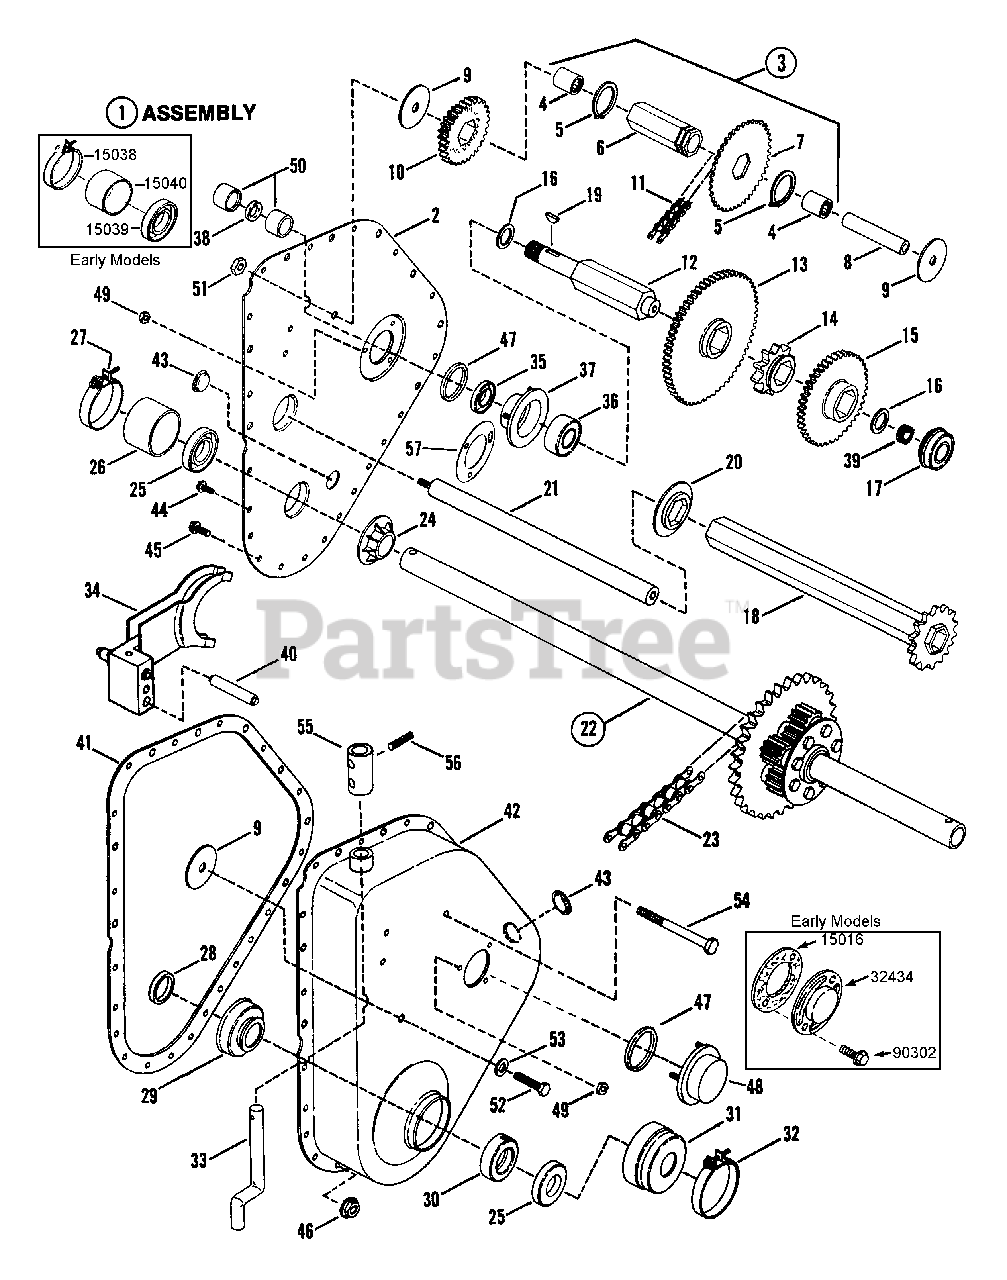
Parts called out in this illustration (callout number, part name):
1	ASSEMBLY, TRANSMISSION (NLA)
2	COVER, Transmission
3	ASSEMBLY, Hex Tube (2.5" Long)
4	BEARING, Needle .8125 OD x .625 ID x .75 Wide
5	RING, Retaining .992 x .052
6	TUBE, Hex 2.5" Long
7	SPROCKET, 46 Tooth (#35)
8	RACE, Bearing 2.525 x .6215
9	THRUST WASHER 1.5 x .390 x .025
10	CLUSTER GEAR
11	CHAIN, 56 Pitch (#35)
12	SHAFT, Third Reduction (6.027" Long)
13	GEAR, 67 Tooth, 12 Pitch
14	SPROCKET, 10 Tooth (#50)
15	GEAR, 47 Tooth, 12 Pitch
16	WASHER, SHIM, .625X.812X.016
17	BEARING, Ball 5/8IDX1-3/8OD
18	ASSEMBLY, Drive Hex Tube 13.2" Long
19	KEY, Woodruff (#9) .188" Thick
20	SPECIAL WASHER (Hex Insert)
21	SHAFT, Drive Tube Support 13.26"
22	DIFFERENTIAL
23	CHAIN, 42 Pitch (#50)
24	SPECIAL WASHER
25	SEAL, 1.22" ID x 1.875" OD
26	CAP, Seal
27	CLAMP, 1-7/8" Hose
28	SPACER, Bearing (.280" thick, use with 1-4400
28	SPACER, Bearing (.145" thick, use with 1-8822)
29	BEARING, Ball, 2.5" OD x 1.21" ID x .987" Thick
30	COLLAR, Lock
31	CAP, Seal .93" ID x 2.625" OD
32	CLAMP, 2.69"
33	ROD, (HI-LO Range) Shift
34	ASSEMBLY, Hl-LO Shifter
35	SEAL, 1.129 OD x .875 ID
36	BEARING, 5/8 ID
37	ASSEMBLY, Bearing Retainer
38	O-RING, 5/8
39	RING, Tolerance .625"
40	GUIDE-PIN, Shift
41	GASKET, Cover to Case
42	ASSEMBLY, Transmission Case (NLA)
43	PLUG, Oil Fill & Check 3/4"
44	SCREW, 1/4-20 x 5/8" HWF Self Tap
45	BOLT, 1/4-20 x 1/2' HWF (2-Locating)
46	NUT, 1/4-20 Hex Flange Lock (for item 45)
47	"O" RING, 1.614 x .070
48	ASSEMBLY, Bearing Retainer
49	NUT, 1/4-20 Hex Flange Lock
50	SPACER, Brake Shaft
51	NUT, 3/8-16 Hex Top Lock
52	SCREW, 3/8-16 x 3/4" Hex Head Cap, Grade 5
53	WASHER, 3/8 Split Lock
54	SCREW, 3/8-1B x 3-1/4" Hex Head Cap
55	COUPLING, Shift Lever
56	ROLL-PIN, 3/16 X 3/4"
57	GASKET, Bearing Retainer
15016	GASKET, BEARING COVER
15038	CLAMP, 1.66"
15039	SEAL, OIL, LT 1.441 x .875
15040	BOOT, OIL SEAL
32434	COVER, BEARING
90302	HWST, 1/4C X3/8 BZ
